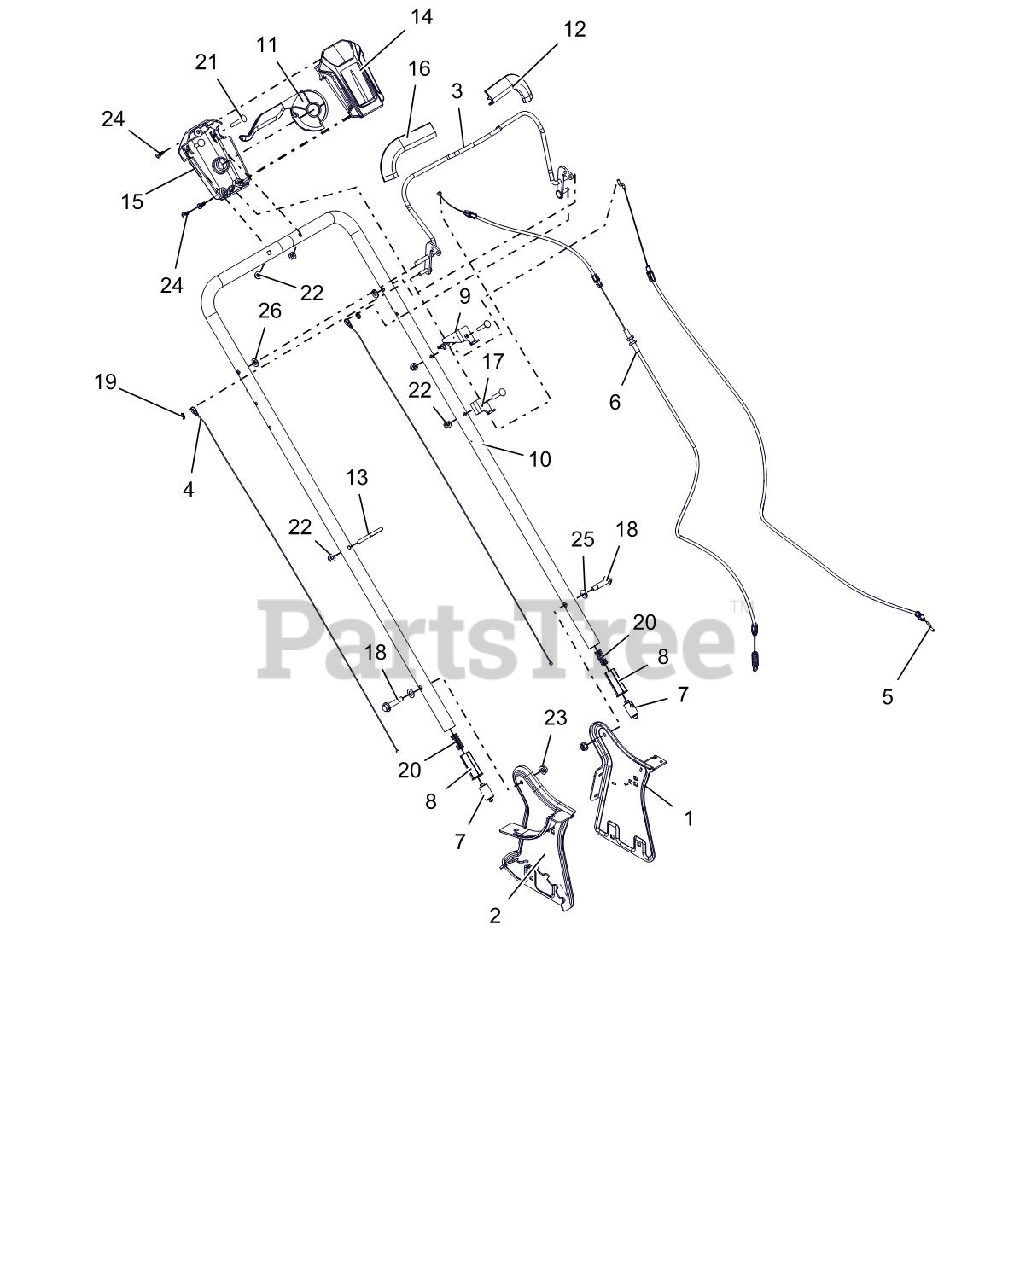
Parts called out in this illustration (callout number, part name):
1	SUPPORT, LH HANDLEBAR
2	SUPPORT, RH HANDLEBAR
3	WLDMT, OPC BAIL
4	CABLE, LM HANDLE ADJUST
5	CABLE, OPC, RAZOR LM
6	CABLE, DRIVE CONTROL
7	PLUNGER, HANDLEBAR LOCKING
8	INSERT, HANDLEBAR ADJUST
9	BRKT, CABLE ANCHOR
10	HANDLEBAR, LM
11	HANDLE, DRIVE CONTROL
12	GUARD, FINGER - LH
13	HOLDER, RECOIL CORD
14	HOUSING, UPPER DRIVE CONTROL
15	HOUSING, LOWER DRIVE CONTROL
16	HAND GRIP W/ DECAL
17	BRKT, CABLE - DRIVE
18	BLT-SHLDR, .50X1.15X.312-18GR5
19	RG-RTNG-EXT .250X.010
20	SPRING, COMPRESSION
21	@BLT-RDHDSQNK .25-20X1.50 G5YZ
22	@NUT-LK-TOP-FLG .25-20 YWZC
23	@NUT-LK-TOP-FLG .31-18 YWZC
24	SCR-TAP 12-14X.75PLSTITE @BLZC
25	WSHR,.385X.745X.030 STL YWZC
26	@WSHR-FL-STL.344X.688X.065YWZC
